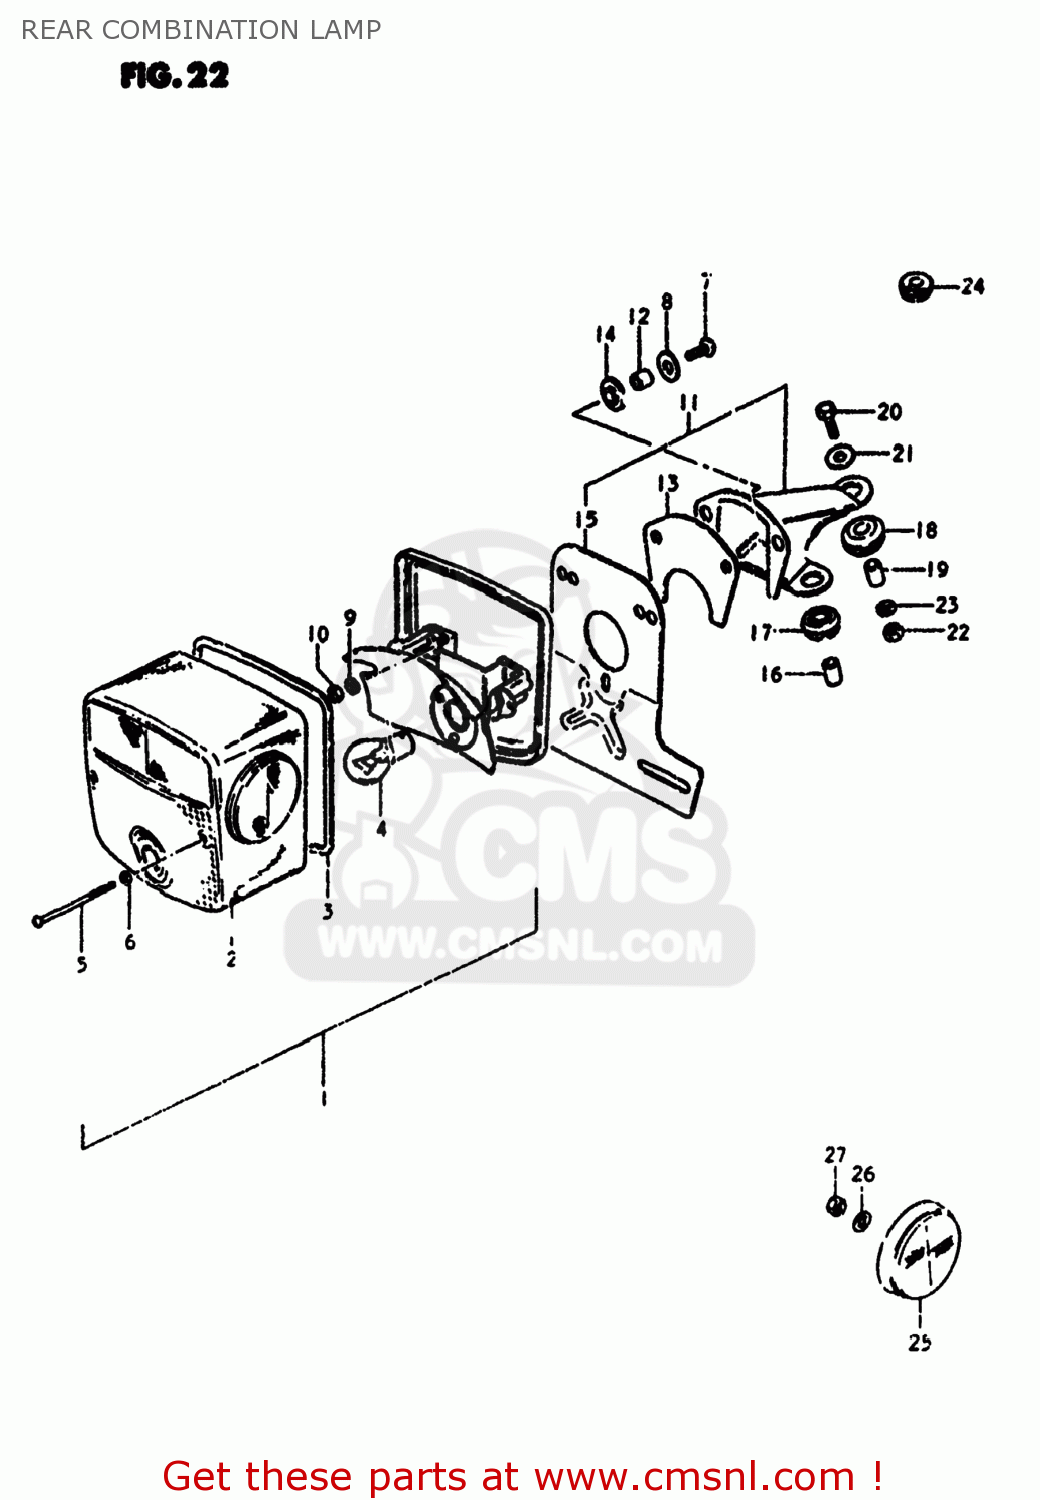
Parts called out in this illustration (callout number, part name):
1	LAMP UNIT,REAR COMBINATION
2	LENS
3	GASKET (NAS)
4	BULB(6V32/3CP,STANLEY)
5	SCREW (4X55)
6	GASKET (NAS)
7	TAPPING SCREW
8	WASHER,REAR COMBINATION LAMP
9	NUT
10	LOCK WASHER
11	BRACKET UNIT,TAIL LAMP
12	SPACER
13	CUSHION
14	CUSHION,REAR COMBINATION LAMP
15	BRACKET,LICENSE PLATE
16	SPACER
17	CUSHION,REAR COMBINATION LAMP
18	CUSHION,REAR COMBINATION LAMP
19	SPACER
20	BOLT
21	WASHER (6.5X20X1.2)
22	NUT
23	WASHER 6MM
24	GROMMET
25	REFLEX REFLECTOR,FR
26	WASHER
27	LOCK WASHER
